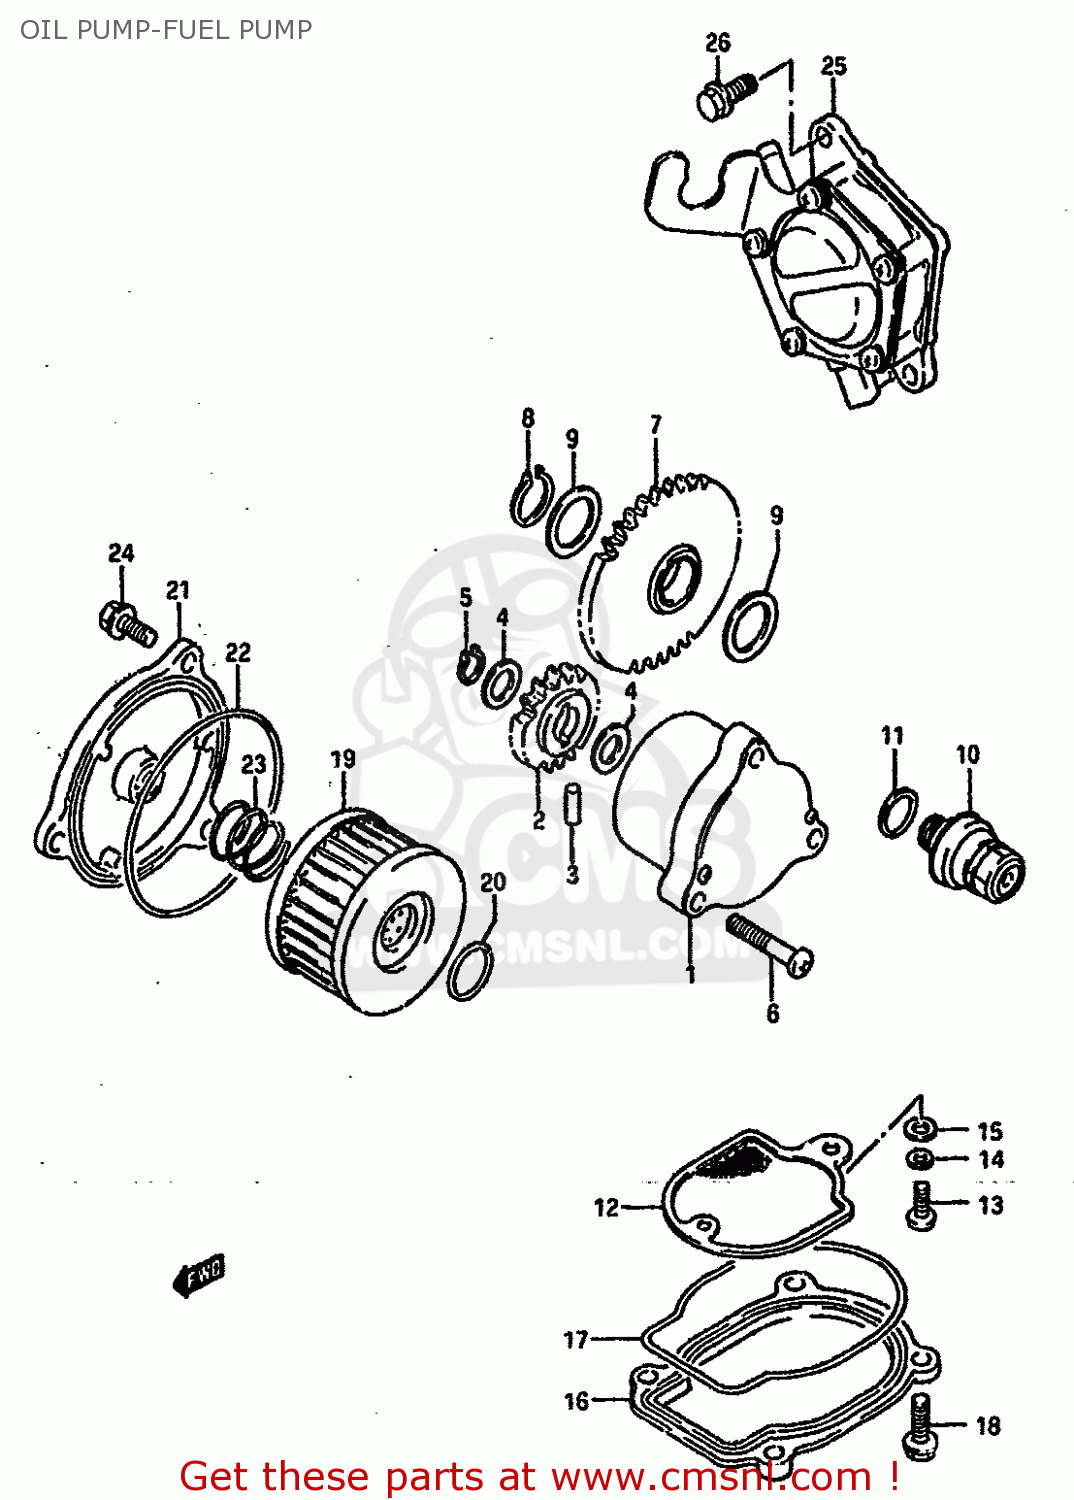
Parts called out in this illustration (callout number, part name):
1	PUMP ASSY,ENGINE OIL
2	GEAR,OIL PUMP DRIVEN(NT:15)
3	PIN(4X15.8)
4	SHIM
5	CIRCLIP
6	SCREW 6X30
7	GEAR,OIL PUMP DRIVE
8	CIRCLIP
9	WASHER
10	VALVE ASSY,OIL RELIEF
11	WASHER
12	STRAINER,ENGINE OIL
13	SCREW 5X12
14	LOCK WASHER
15	WASHER
16	CAP,OIL STRAINER
17	O RING,OIL STRAINER CAP
18	BOLT 6X20
19	FILTER,ENGINE OIL
20	O RING(D:2.4,ID:15.8)
21	CAP,OIL FILTER (BLUE)
22	O RING(D:2.4,ID:73)
23	SPRING
24	BOLT
25	PUMP ASSY,FUEL
26	BOLT
